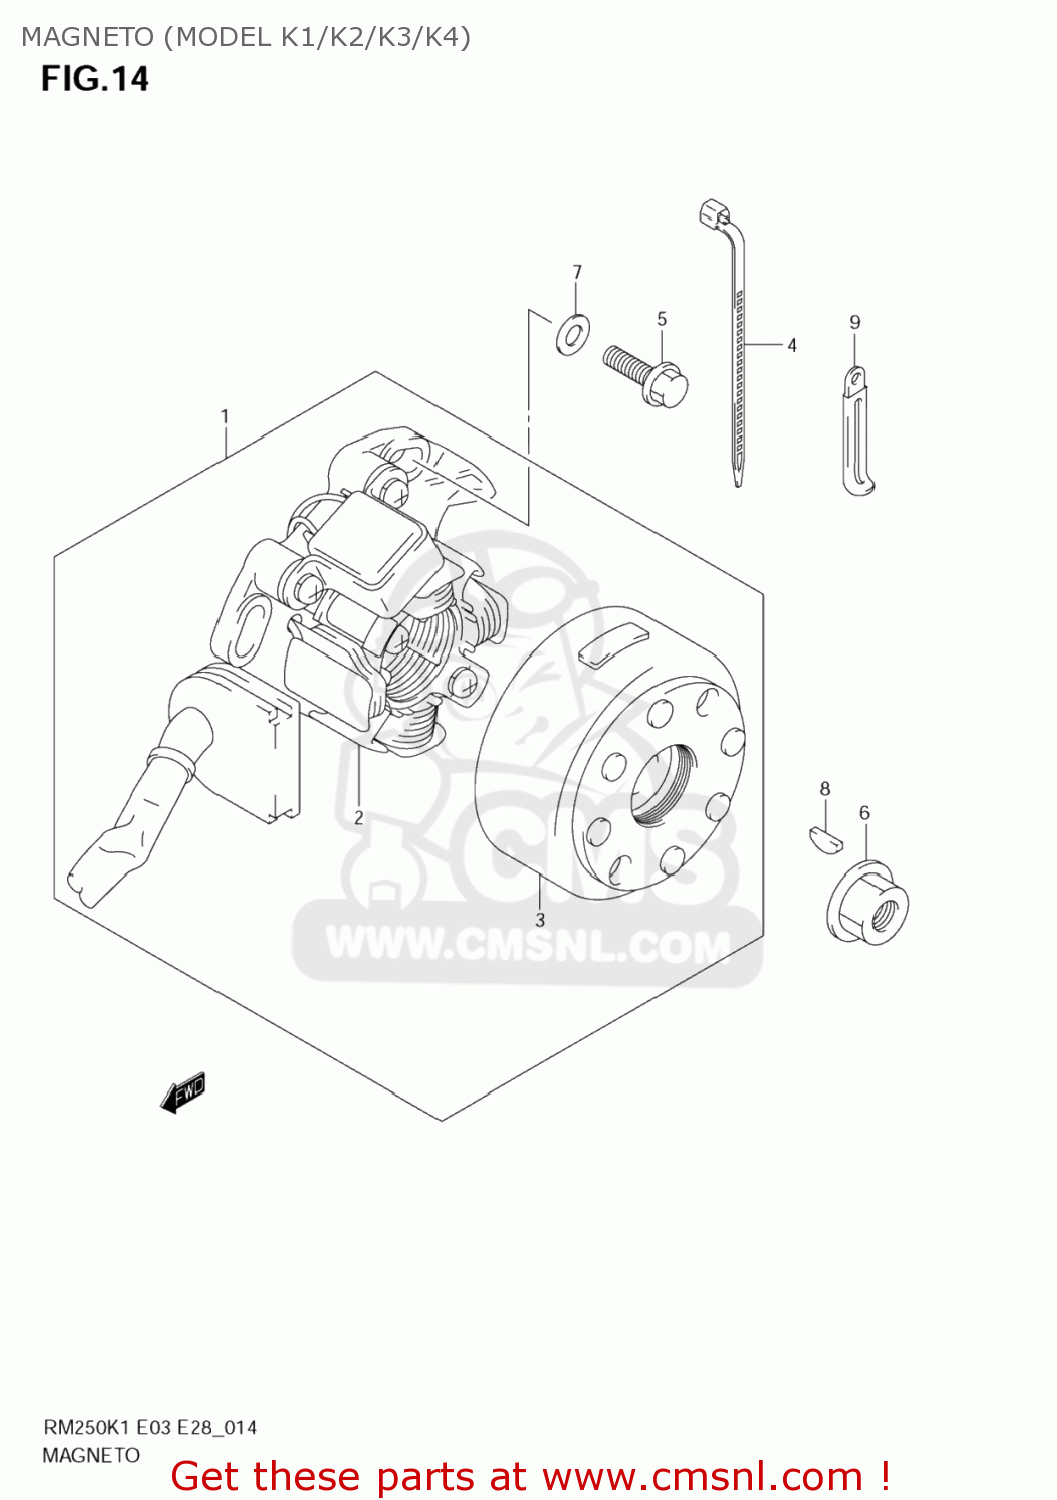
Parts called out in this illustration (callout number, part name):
1	MAGNETO ASSY
2	STARTER ASSY
3	ROTOR ASSY
4	CLAMP(L:165)
5	SCREW
6	NUT
7	WASHER
8	KEY
9	CLAMP(L:45)
